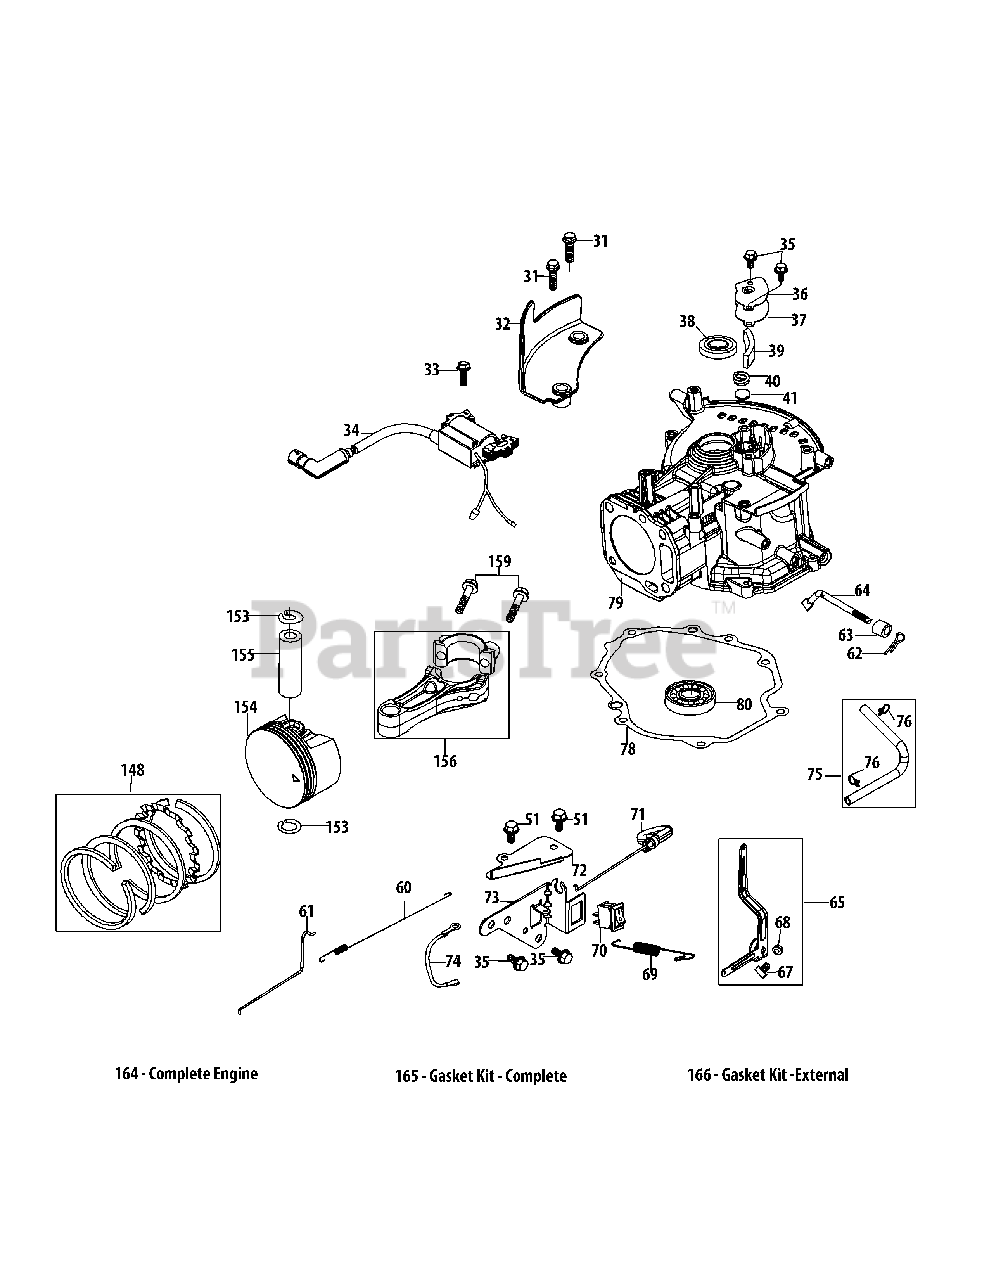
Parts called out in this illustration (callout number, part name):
31	Bolt M6×25 Cover Plate
32	Engine Brake Cover Plate
33	Bolt M6×20 Ignition Coil
34	Ignition Coil Assembly
35	Bolt M6X14 Multi-Purpose
36	Breather Cover Plate
37	Breather Gasket
38	Upper Crankshaft Seal
39	Breather Screen
40	Breather Valve Spring
41	Breather Valve
51	Bolt M6X12 Multi-Purpose
60	Throttle Linkage Spring
61	Throttle Linkage
62	Governor Arm Shaft Cotter Pin
63	Governor Seal
64	Governor Arm Shaft
65	Governor Arm Assembly
67	Governor Arm Bolt
68	Governor Arm Nut M6
69	Governor Spring
70	Ignition Switch
71	Choke Control
72	Air Vane Cover Plate
73	Component Bracket
74	Ignition Switch Ground Wire
75	Breather Hose Assembly
76	Breather Hose Clamp
78	Crankcase Cover Gasket
79	Short Block
80	Main Bearing
148	Piston Ring Set
153	Piston Pin Snap Ring
154	Piston
155	Piston Pin
156	Connecting Rod Assembly
159	Connecting Rod Bolt
164	Complete Engine
165	Gasket Kit - Complete
166	Gasket Kit -External
